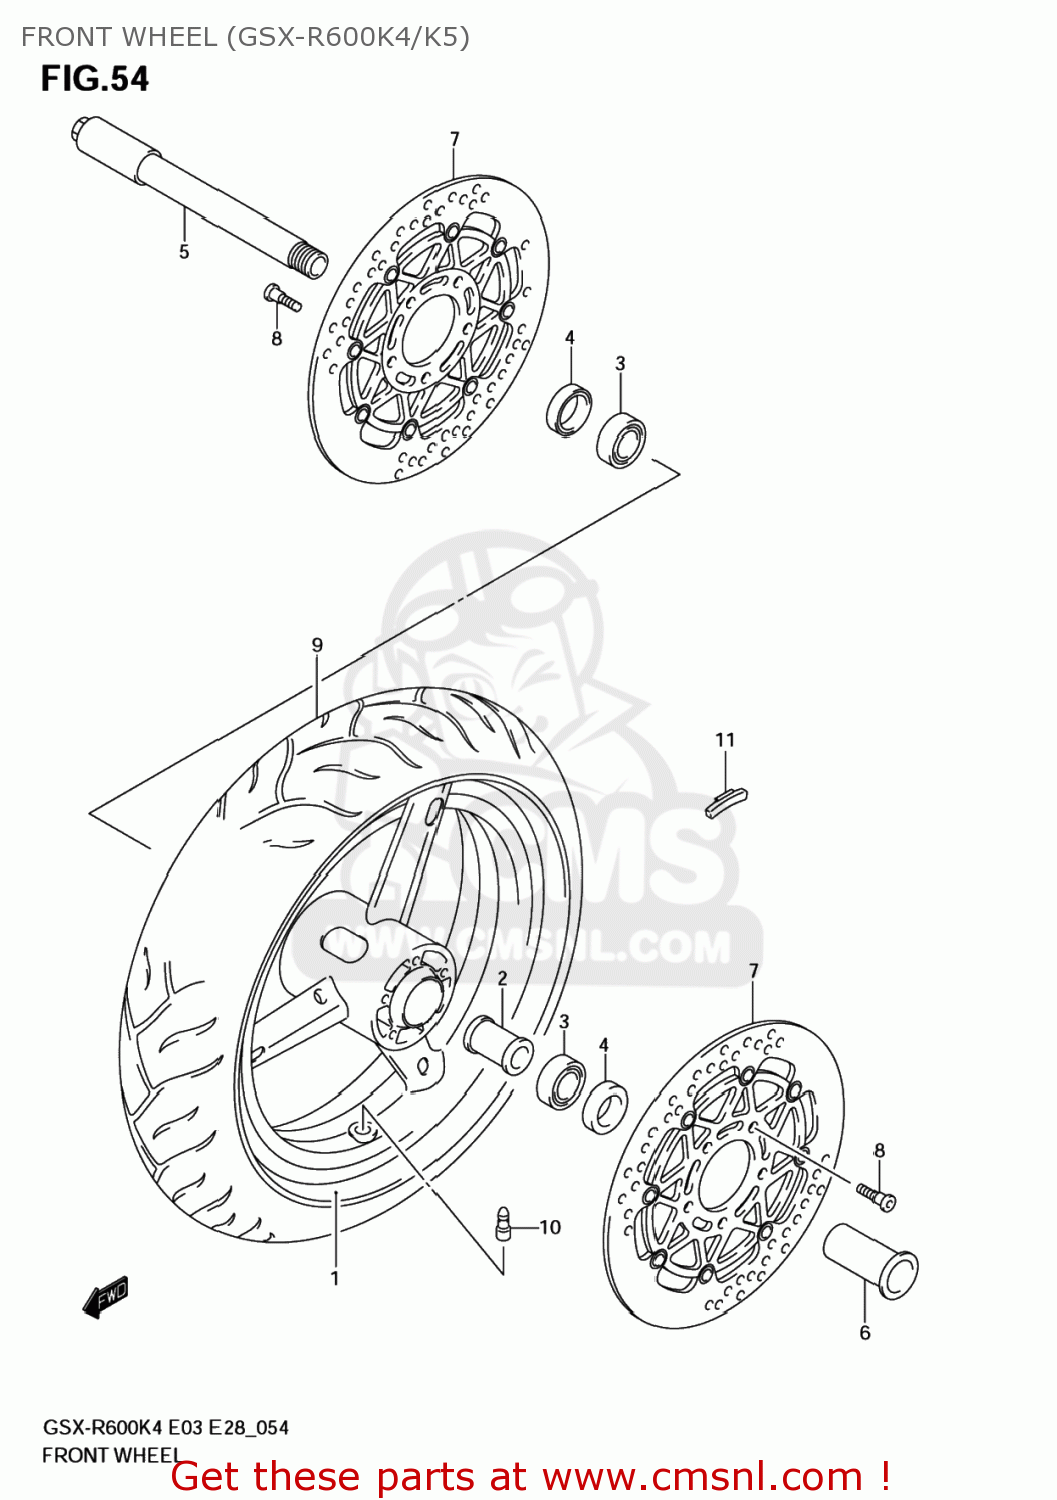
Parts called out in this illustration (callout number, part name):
1	WHEEL,FR(17M/CXMT3.50)
2	SPACER,FR HUB BEARING
3	BEARING(25X52X15)
4	SEAL,OIL(32X52X7)
5	AXLE,FR
6	NUT,FR AXLE
7	DISC,FR BRAKE
8	BOLT(8X33)
9	TIRE, FRONT 120/70 ZR17 (58W)
10	VALVE ASSY,WHEEL RIM(TR412)
11	WEIGHT,WHEEL BALANCE 10G
